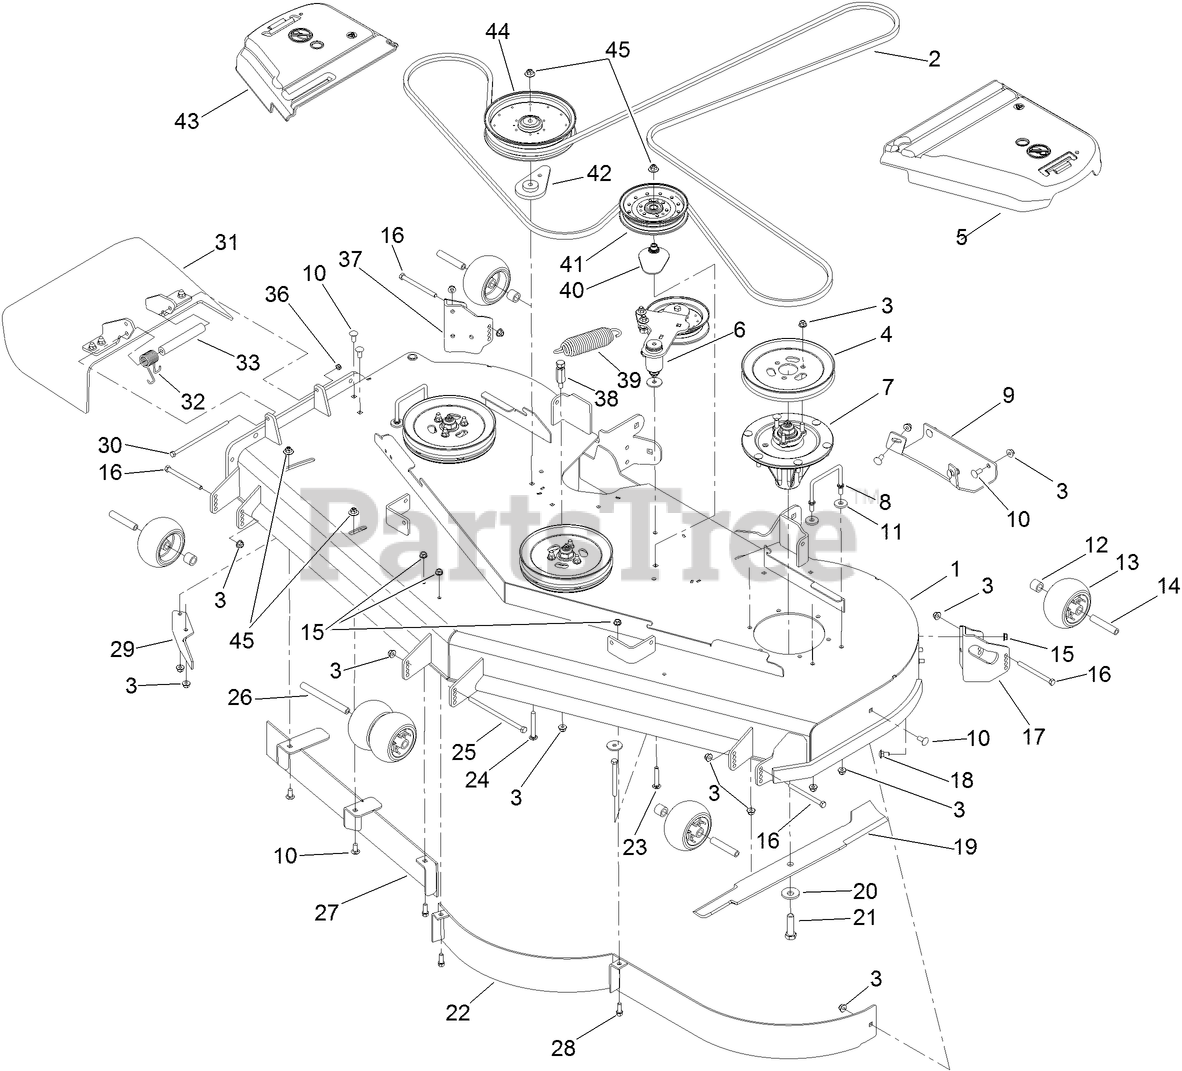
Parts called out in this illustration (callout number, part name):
1	DECK DECAL ASM
2	BELT-V
3	NUT-HF, NI
4	Pulley
5	COVER-BELT, LH
6	IDLER ARM ASM
7	SPINDLE ASM
8	WIREFORM-COVER
9	PLATE-SKID
10	SCREW-CARR
11	WASHER
12	TUBE-SPACER
13	ROLLER-SCALP, ANTI
14	TUBE-SPANNER
15	NUT-HHF, WHIZ
16	SCREW-HH
17	MOUNT-WHEEL, LH
18	SCREW-CARR
19	BLADE-HI FLOW, 24.5 INCH
20	Washer-Blade Bolt, Heavy
21	SCREW-BLADE
23	BOLT-CARR, SHORT NECK
24	SCREW-CARR
25	SCREW-HH
26	SPACER-WHEEL
28	SCREW-HWH
29	BAFFLE-DISCHARGE
30	SCREW-HH
31	RUBBER DEFLECTOR ASM
32	SPRING-TORSION
33	SPACER
36	NUT-LOCK, NI
37	MOUNT-WHEEL, RH
38	ANCHOR-SPRING, TALL
39	SPRING-EXTENSION
40	SPACER-PULLEY
41	PULLEY-IDLER, FLAT
42	SPACER-IDLER
43	COVER-BELT, RH
44	PULLEY-IDLER
45	NUT-FLANGE, NI
